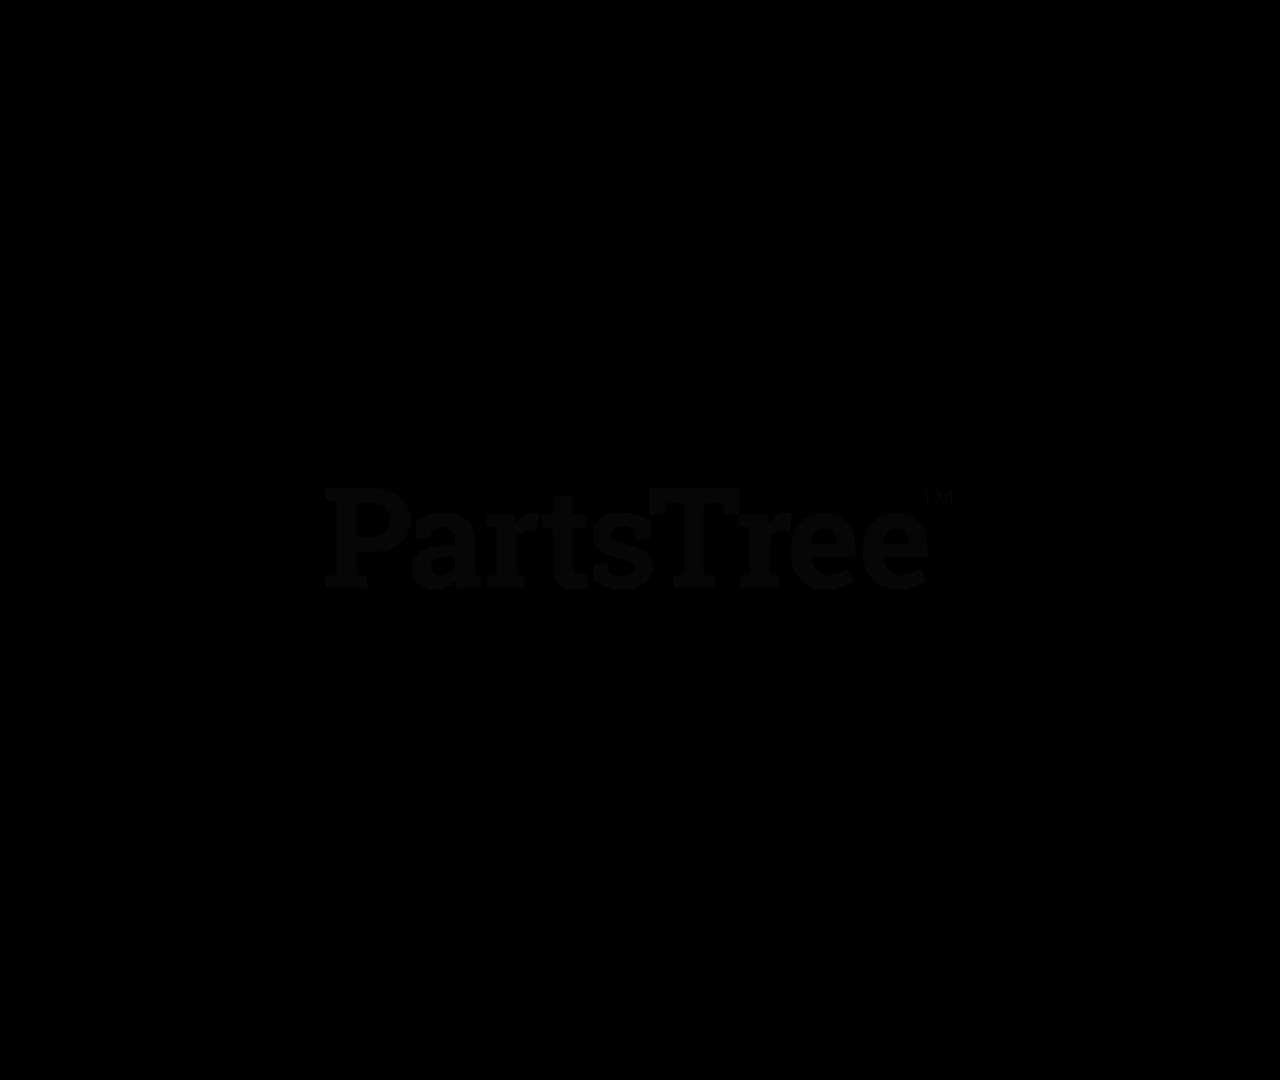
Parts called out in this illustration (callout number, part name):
2	SCREW - 5×16
3	GRIP, HANDLE - RIGHT
5	SPRING, THROTTLE LOCK
6	LOCKOUT, TRIGGER
8	CONTROL CABLE ASY
9	SCREW - 5×35
10	WASHER - 5
11	LOCKNUT - 5
12	TIE, CABLE
13	BRACKET, THROTTLE CONTROL - LEFT
14	SCREW - 4×25
15	SCREW - 4×30
16	IGNITION SWITCH ASY
17	TRIGGER, THROTTLE
18	SPRING, TRIGGER
19	BRACKET, THROTTLE CONTROL - RIGHT
20	HANDLE - REAR
